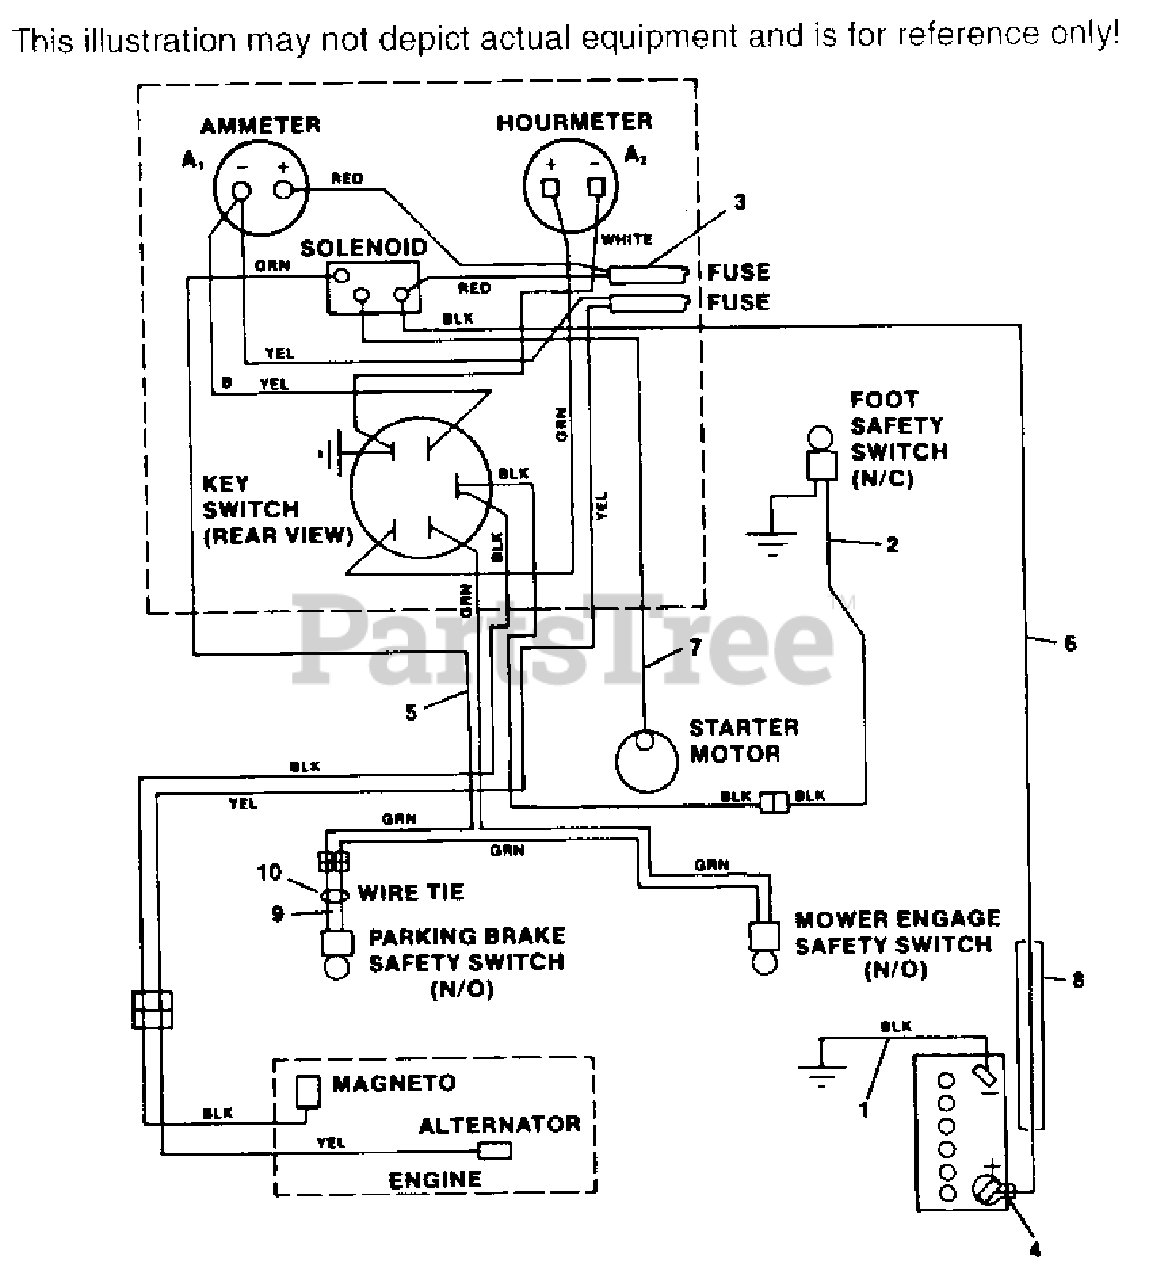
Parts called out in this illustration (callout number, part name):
1	BATTERY CABLE GROUND
2	WIRE HARNESS, FOOT SAFETY SWITCH
3	WIRE HARNESS, SOLENOID TO AMMETER
4	RUBBER BOOT
5	WIRE HARNESS
6	BATTERY CABLE, LONG
7	BATTERY CABLE, SHORT
8	CONDUIT, BLACK NYLON 10"
9	WIRE EXTENSION
10	CABLE TIE
